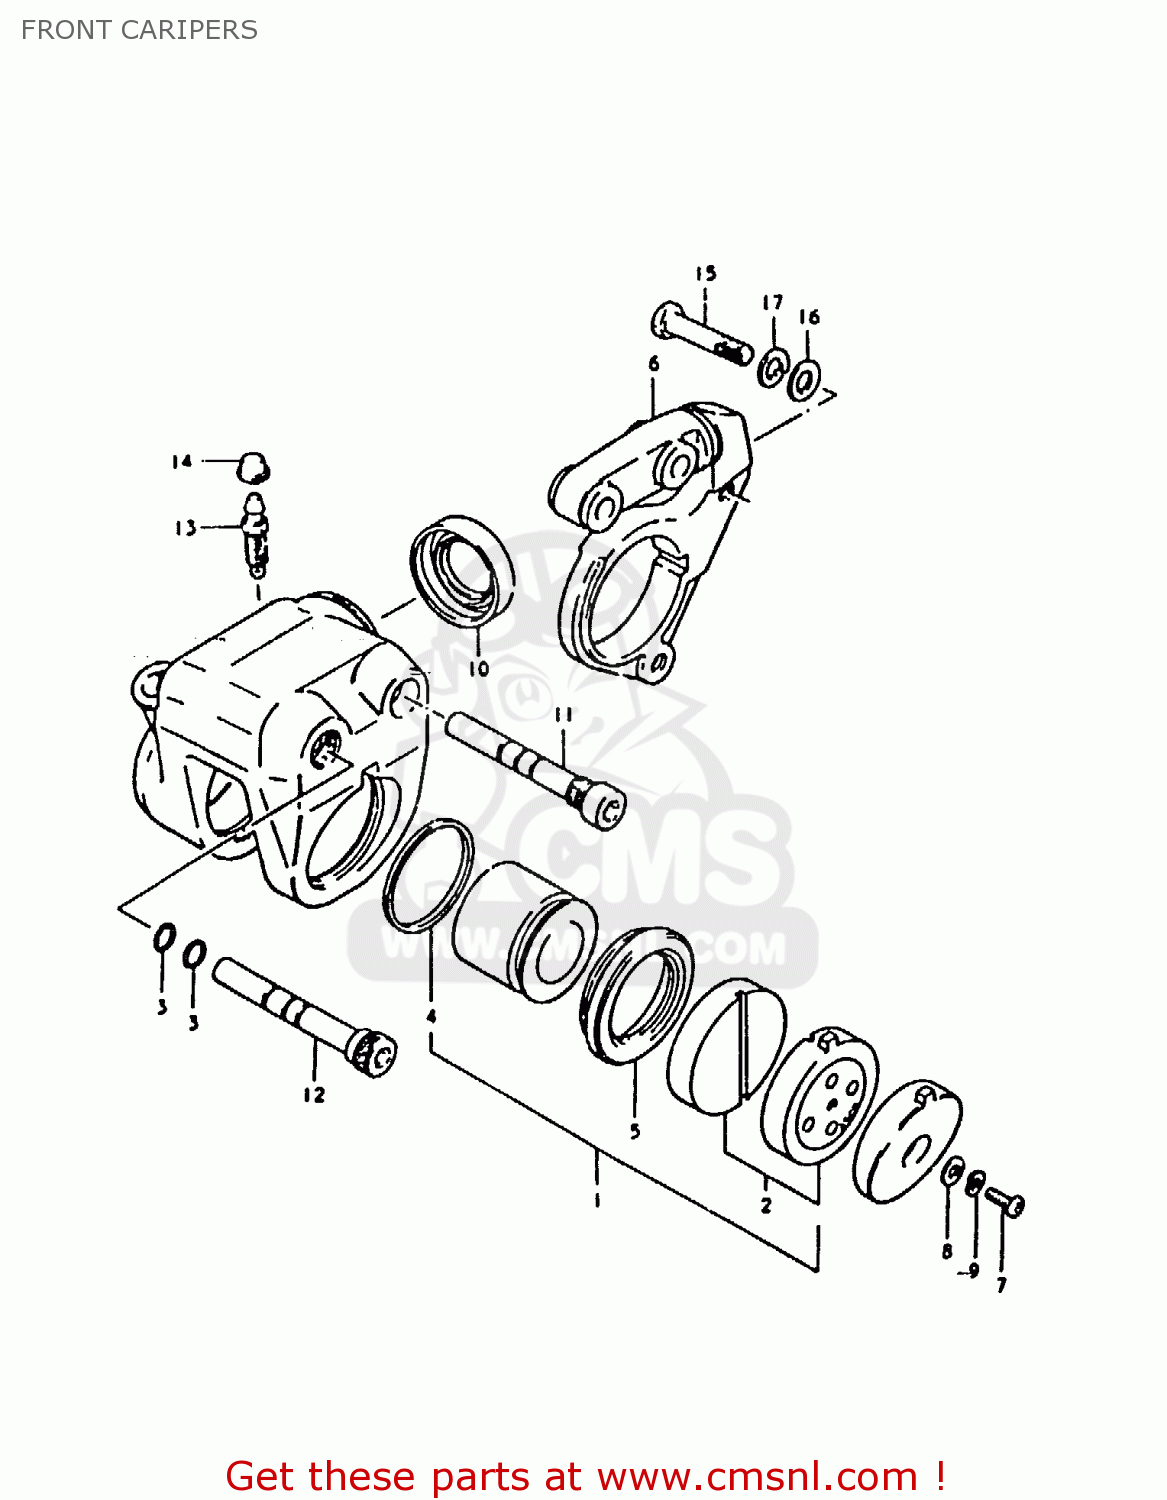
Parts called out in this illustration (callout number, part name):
1	PISTON & PAD SET
2	PAD SET (MCA)
3	O RING,AXLE CALIPER
4	SEAL,PISTON
5	BOOT,PISTON
6	HOLDER,CALIPER
7	SCREW
8	WASHER
9	LOCK WASHER
10	BOOT,HOLDER
11	AXLE,CALIPER
12	AXLE NO.2
13	BLEEDER
14	CAP,BLEEDER PL
15	BOLT
16	WASHER
17	LOCK WASHER
